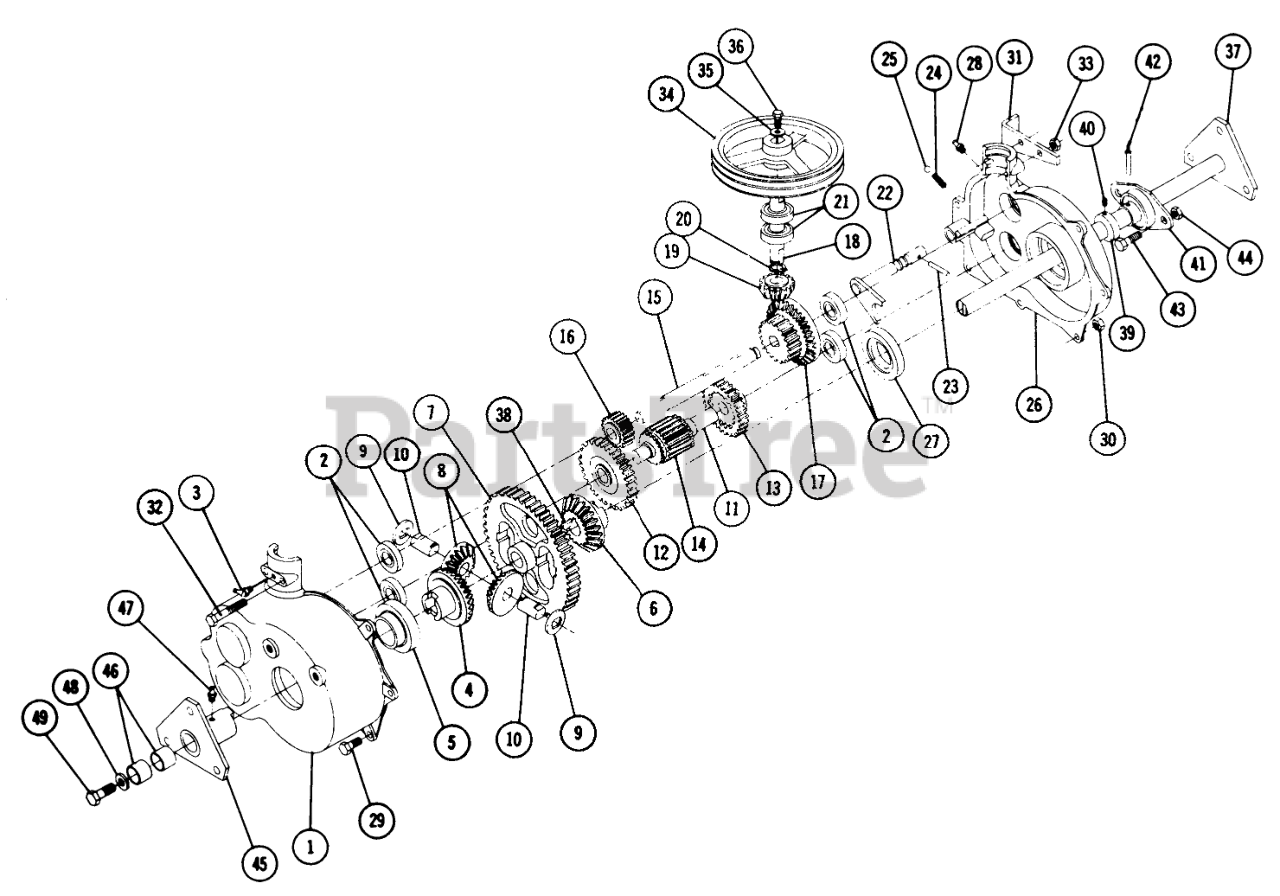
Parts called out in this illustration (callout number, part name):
3	FITTING-GREASE
20	SNAP RING- 5/8 EXT
23	PIN-SPIROL
25	BALL-DETENT
29	Bolt, 5/16-18 X 7/8
30	Nut 5/16-18 Keps
31	Bracket Shift Rod
32	Bolt Hex 5/6-18 X 2-1/2
33	Nut-Nylok
35	Washer
36	Bolt, 5/16-18 x 5/8
38	WOODRUFF KEY
40	Set Screw Nylok
42	Spirol Pin
43	Bolt Hex 3/8-16 x 5/8
46	BUSHING-BRONZE
47	Fitting
48	WASHER
49	Bolt 3/8-16 x 3/4 Hex
49	Bolt 3/8-16 x 3/4
49	Lockwasher-3/8 Int. Tooth
